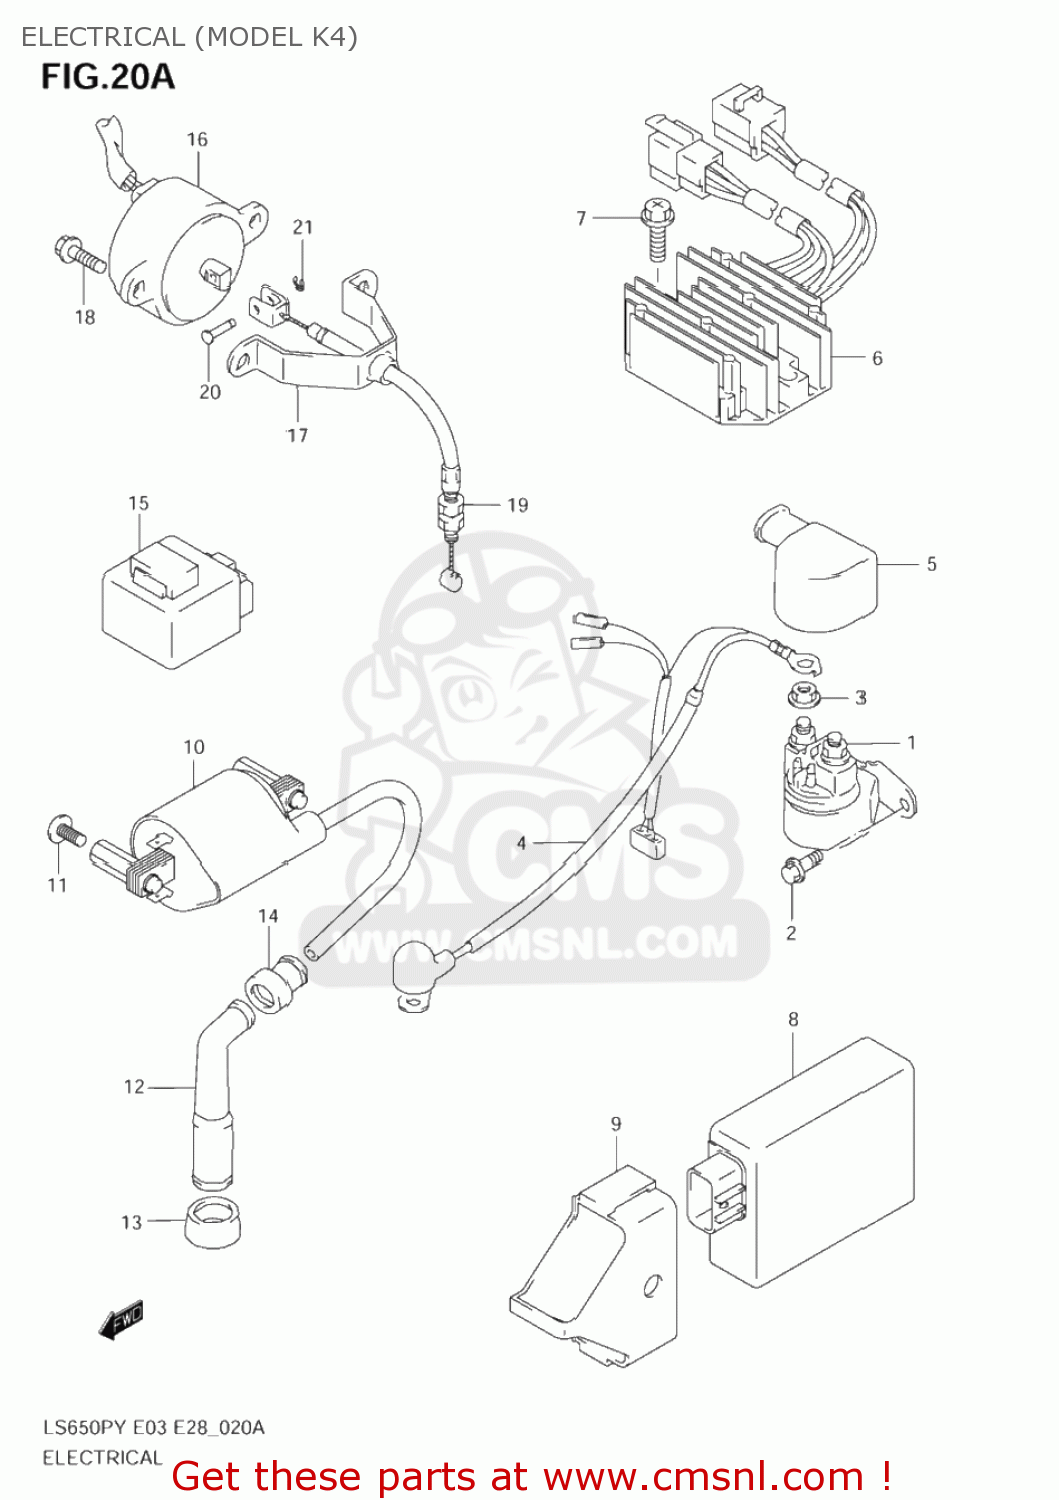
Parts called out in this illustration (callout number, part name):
1	RELAY ASSY,STARTING MOTOR
2	BOLT
3	NUT
4	WIRE,STARTER MOTOR
5	CAP,STARTER RELAY TERMINAL
6	RECTIFIER ASSY
7	BOLT
8	IGNITOR ASSY
9	CUSHION,IGNITOR
10	COIL ASSY,IGNITION
11	SCREW 5X12
12	CAP ASSY,SPARK PLUG
13	SEAL,SPARK PLUG
14	SEAL,HIGH TENSION CORD
15	CONTROL UNIT,DECOMP
16	SOLENOID ASSY,DECOMP
17	BRACKET,DECOMP SOLENOID
18	BOLT
19	CABLE ASSEMBLY,DECOMPRESSION
20	PIN(4X12.5)
21	E RING
